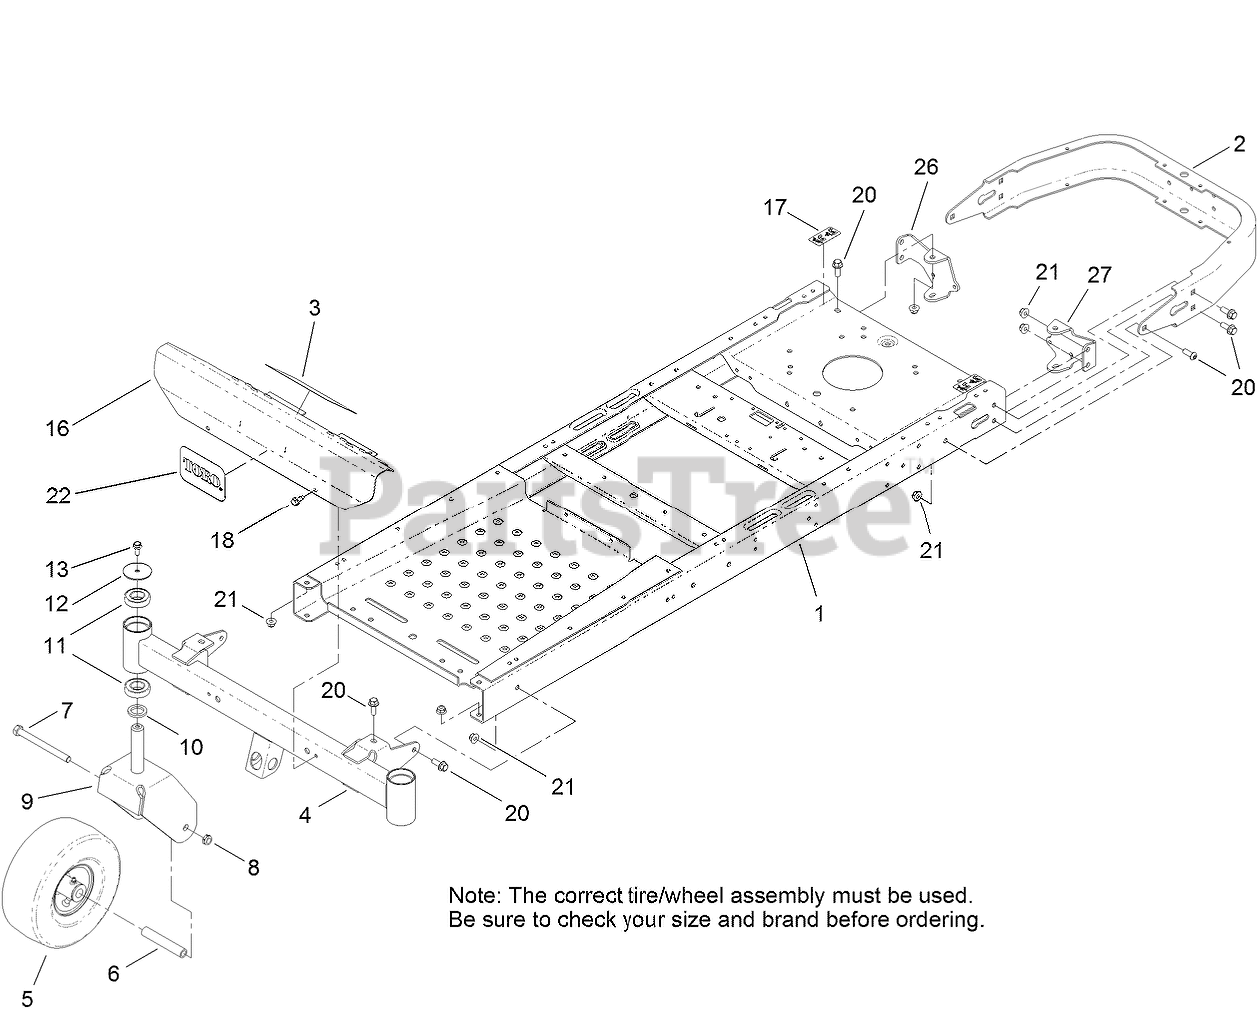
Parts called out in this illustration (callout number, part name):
2	BUMPER-REAR
3	DECAL-DANGER
4	AXLE-FRONT
5	CASTER WHEEL ASM (CST)
5	CASTER WHEEL ASM (Kenda)
6	BUSHING-SPANNER
7	SCREW-HH
8	NUT-LOCK, NI
9	FORK-CASTER
10	WASHER-THRUST
11	BEARING-BALL
12	WASHER
13	SCREW-HHF
16	FOOTREST
17	DECAL-BYPASS
18	SCREW-HWHTF
20	SCREW-HHF
21	NUT-HF, NI
26	MOUNT-HYDRO, REAR (RH)
27	MOUNT-HYDRO, REAR (LH)
